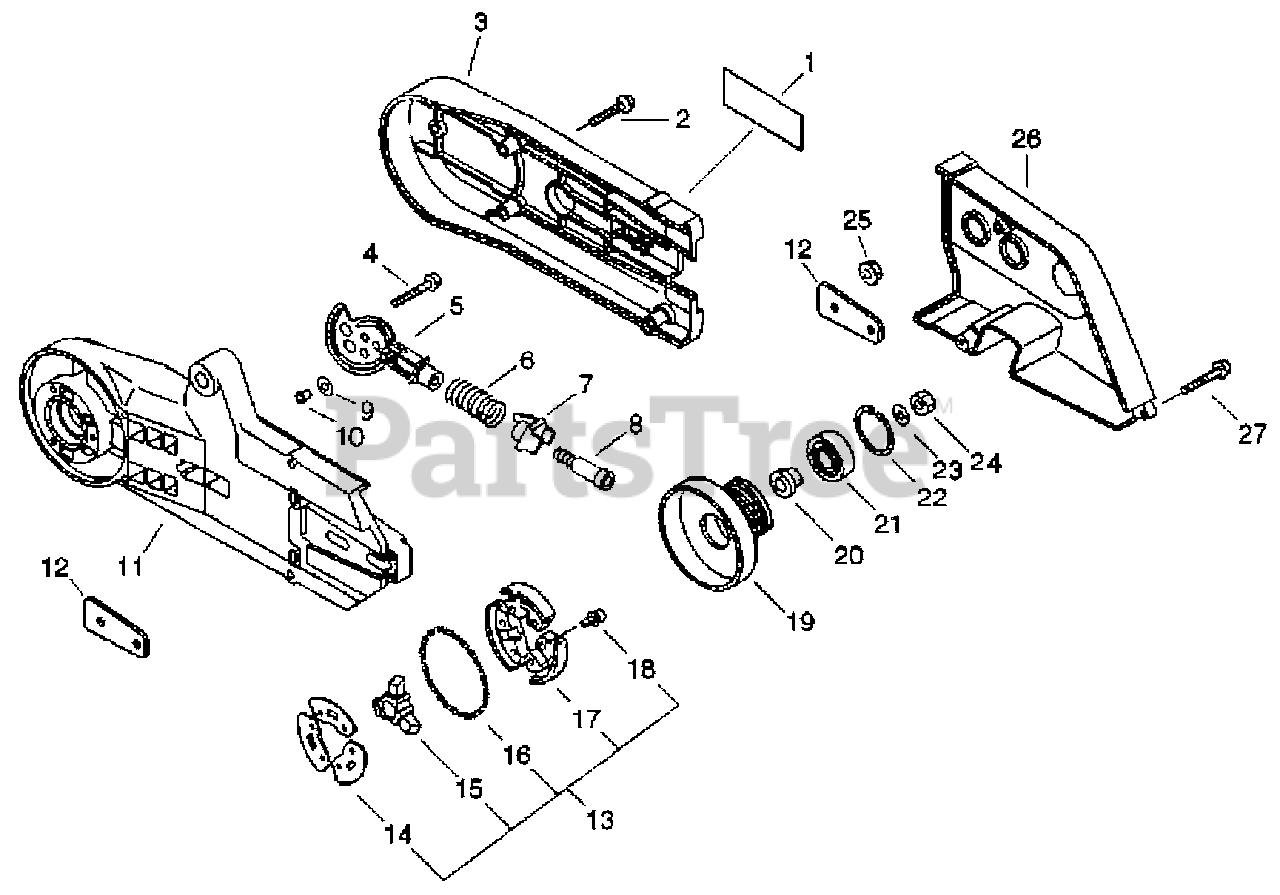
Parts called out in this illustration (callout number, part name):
1	LABEL - ECHO
2	SCREW - 5X25
3	COVER, CUTTER ARM
4	SCREW - 5X25
5	SHAFT, ARM ADJUST
6	SPRING, ADJUST
7	SEAT, SPRING
8	SCREW - 5
9	WASHER - SPRING
11	ARM, CUTTER
12	SPACER, ARM
13	CLUTCH ASSY
14	PLATE, CLUTCH
15	HUB, CLUTCH
16	SPRING, CLUTCH
17	CLUTCH SHOE SET
18	SCREW - 4X6
19	DRUM, CLUTCH
20	COLLAR - 10
21	BEARING, BALL - 6001DDUC3
22	RING, RETAINING - 28
23	WASHER - 8
24	NUT - 8 -- LEFT HAND
25	NUT - 8 -- FLANGE
26	COVER, V-BELT
27	SCREW - 5X25
